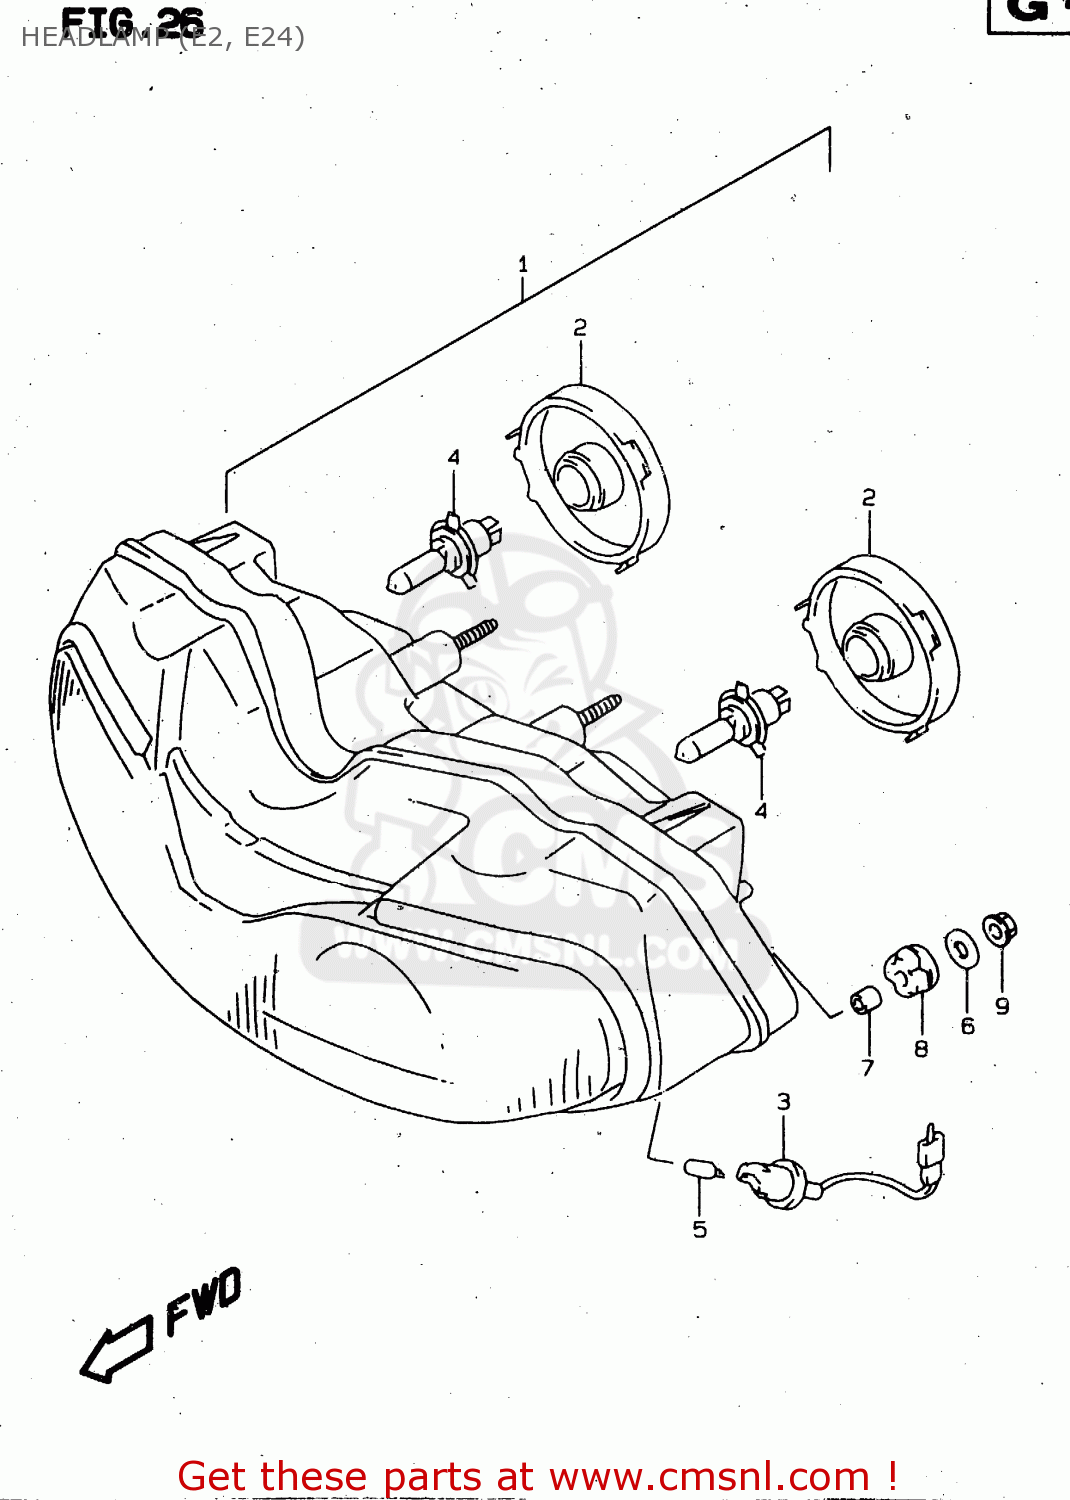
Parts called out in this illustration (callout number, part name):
1	HEADLAMP ASSY
2	COVER,SOCKET
3	SOCKET ASSY
4	BULB(12V60/55W,H4)
5	BULB(12V5W)
6	WASHER(6.5X20X1.6)
7	SPACER(6.5X9X12.5)
8	CUSHION
9	NUT
